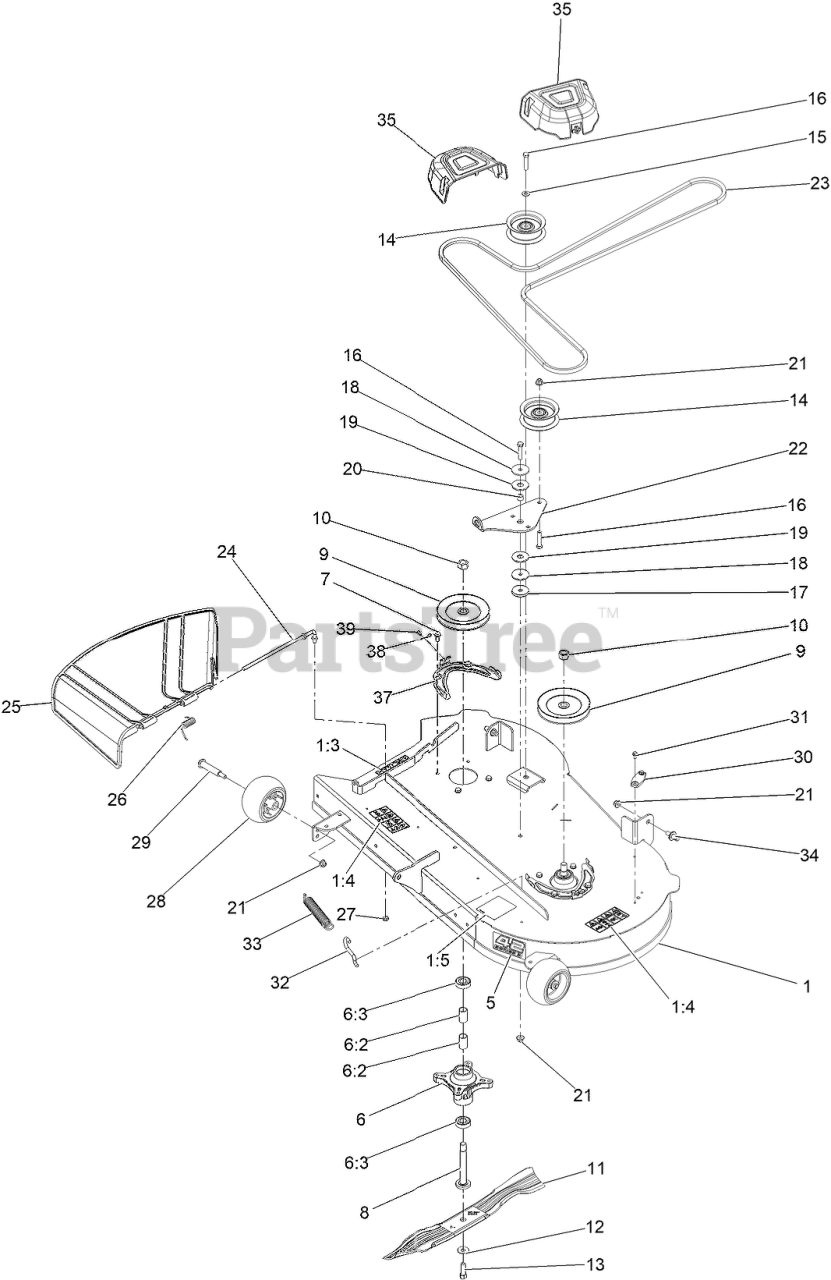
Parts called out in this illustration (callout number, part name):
1	42IN DECK AND DECAL ASM
1:3	DECAL-DANGER
1:4	DECAL-DANGER, DECK
1:5	DECAL-ROUTING, BELT
5	Decal, 42 Series 2
6	SPINDLE ASM
6:3	BEARING-BALL
7	SCREW-TAPTITE
8	SHAFT-SPINDLE
10	NUT-HEX
11	BLADE-21.6 IN
12	WASHER-BELLEVILLE
13	SCREW-HH
14	PULLEY-IDLER, FLAT
15	WASHER-FLAT
16	SCREW-HH
17	WASHER-PLAIN
18	WASHER-REBOUND
19	WASHER-FRICTION, COMPOSIT
21	NUT-HF, NI
22	Arm-Idler
23	V-BELT
24	ROD-PIVOT
25	DEFLECTOR-DISCHARGE
26	SPRING-TORSION
28	ROLLER-SCALP, ANTI
29	BOLT-SHOULDER
30	COVER-WASHOUT PORT
31	SCREW-HWH
32	Hook-Return Spring
33	SPRING EXTENSION
34	PIN-DECK
35	COVER-BELT
37	BRACKET-COVER, BELT
38	PIN-HAIR
